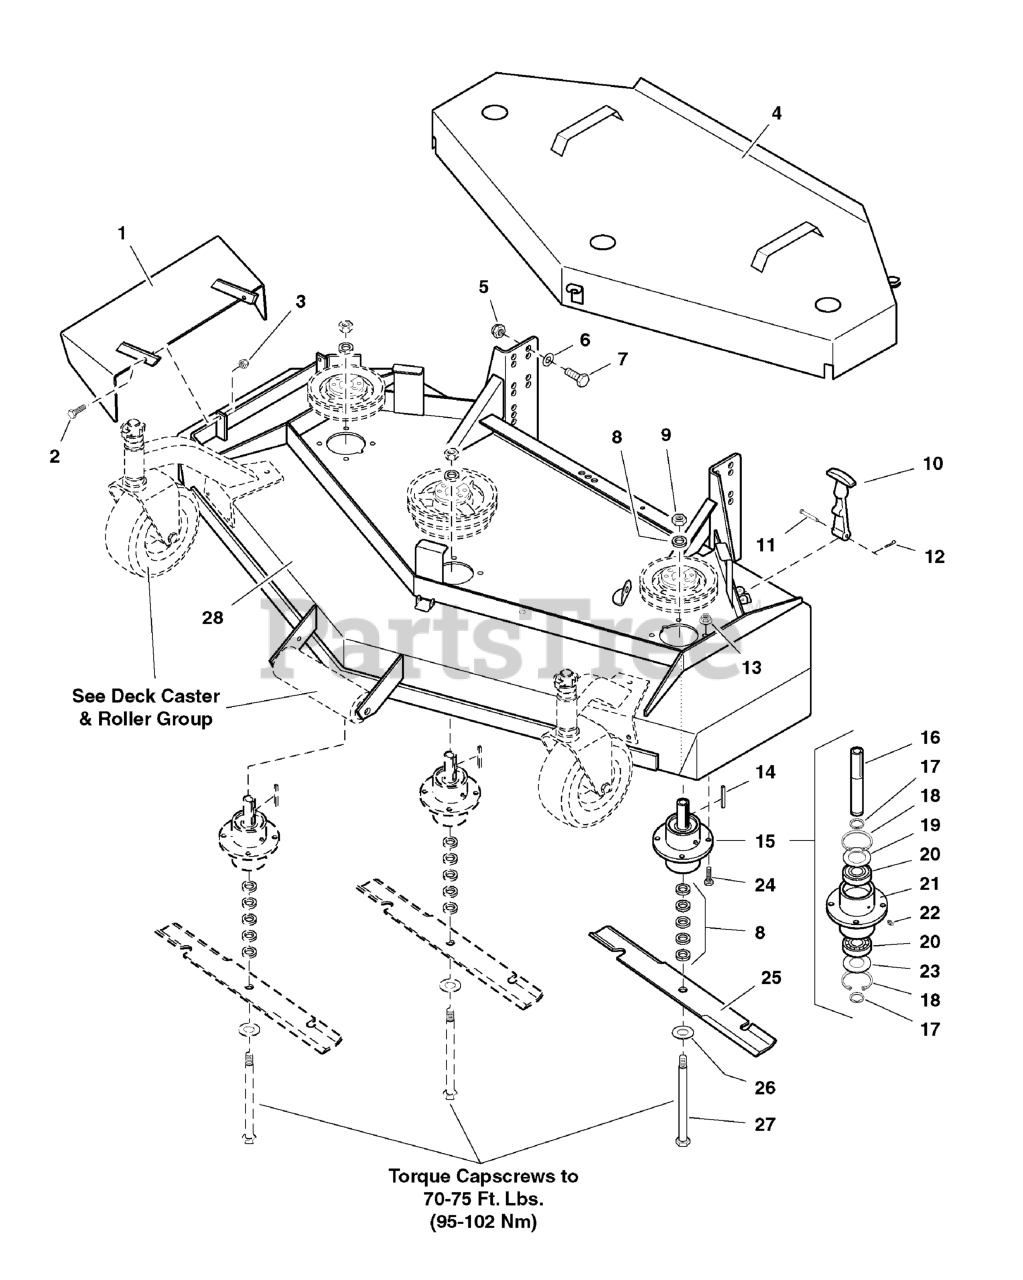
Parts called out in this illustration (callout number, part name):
1	CHUTE, DISCHARGE WELDMENT
2	BOLT, 5/16-18 X 1 GD5 YZ
3	NUT, 5/16-18 Hex Nylon Lock
4	61" SPINDLE COVER
5	NUT, Hex, Nylon Lock, 1/2-20
6	WASHER, 1/2 SAE
7	BOLT, 1/2-20 X 1-1/4" GD5 CZ
8	SPACER, .63 x 1.06 x .23
9	NUT, 5/8-11 Hex
10	RUBBER LATCH
11	CLEVIS PIN
12	COTTER PIN
13	NUT, 5/16-18 HEX SERRATED FLANGE (LARGE)
14	KEY, 1/4 SQ. X 2-1/2
15	SPINDLE ASSEMBLY, Complete
16	SPINDLE SHAFT
17	SNAP RING, External
18	SNAP RING, Internal
19	SPINDLE WASHER, Top
20	BEARING
21	SPINDLE HOUSING
22	GREASE FITTING
23	SPINDLE WASHER, Bottom
24	BOLT, 5/16-18 x 1-1/4
25	MOWER BLADE, 21"
26	WASHER, 5/8" USS
27	BOLT, 5/8-11 x 9-1/2
28	DECK SHELL W/DECALS, 61"
